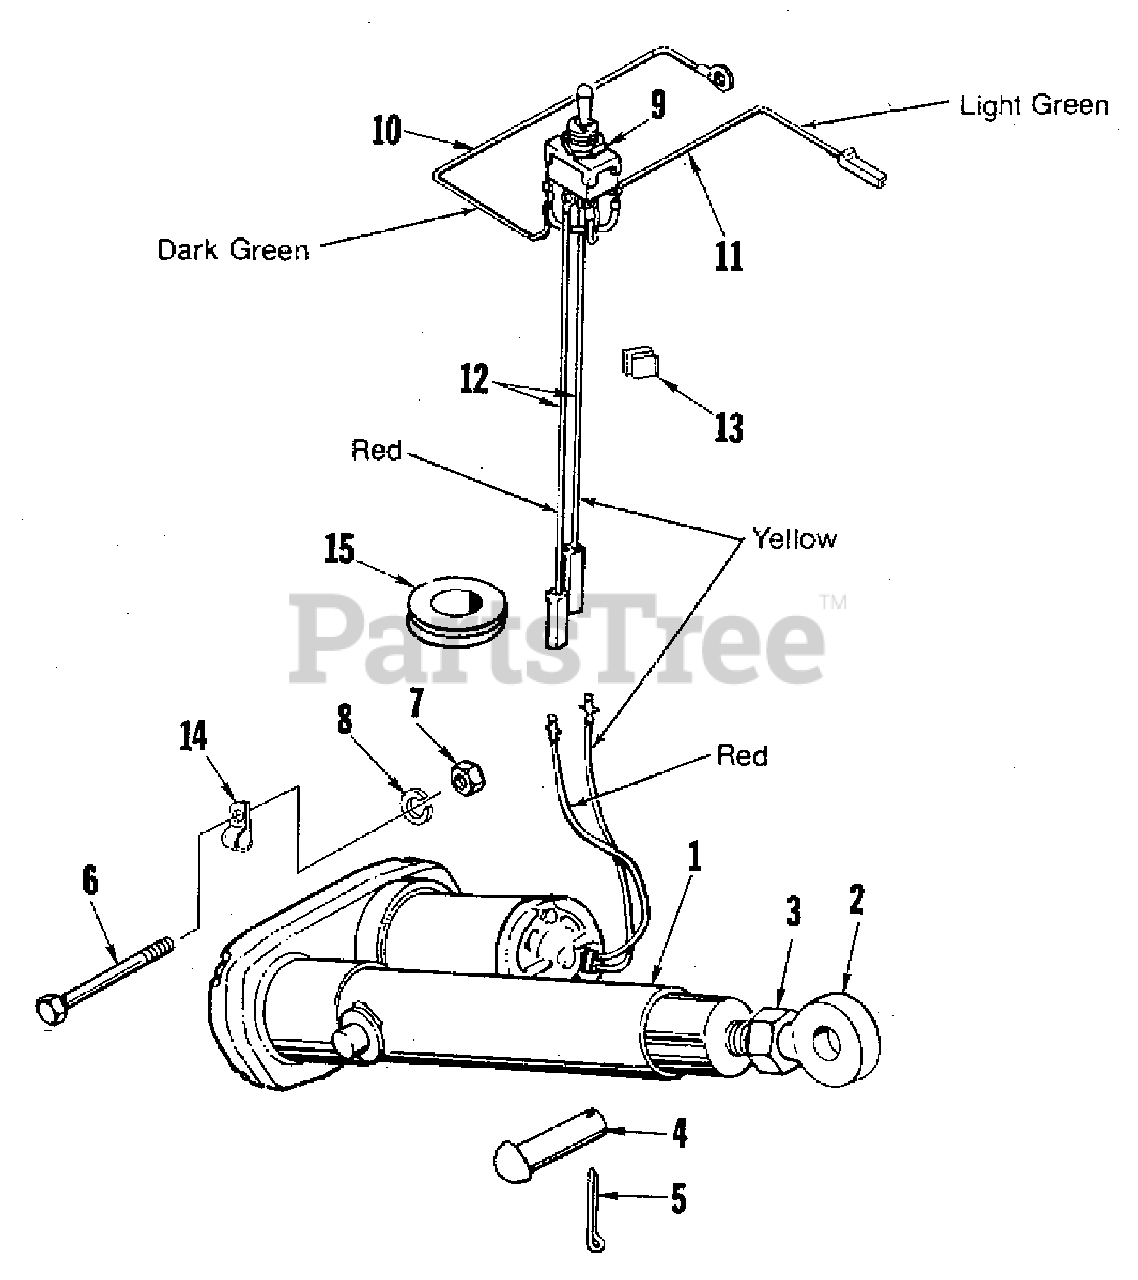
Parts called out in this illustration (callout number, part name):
1	ACTUATOR, Electric
3	NUT, Jam Hex
6	SCREW, Hex Head, Cap
7	NUT, Hex Fin.
8	WASHER, Lock
9	SWITCH, Toggle
10	LEAD, Switch Connector
11	LEAD, Actuator Switch To PTO Switch
12	HARNESS, Switch to Actuator
14	CLIP, Closed
15	GROMMET, Rubber
